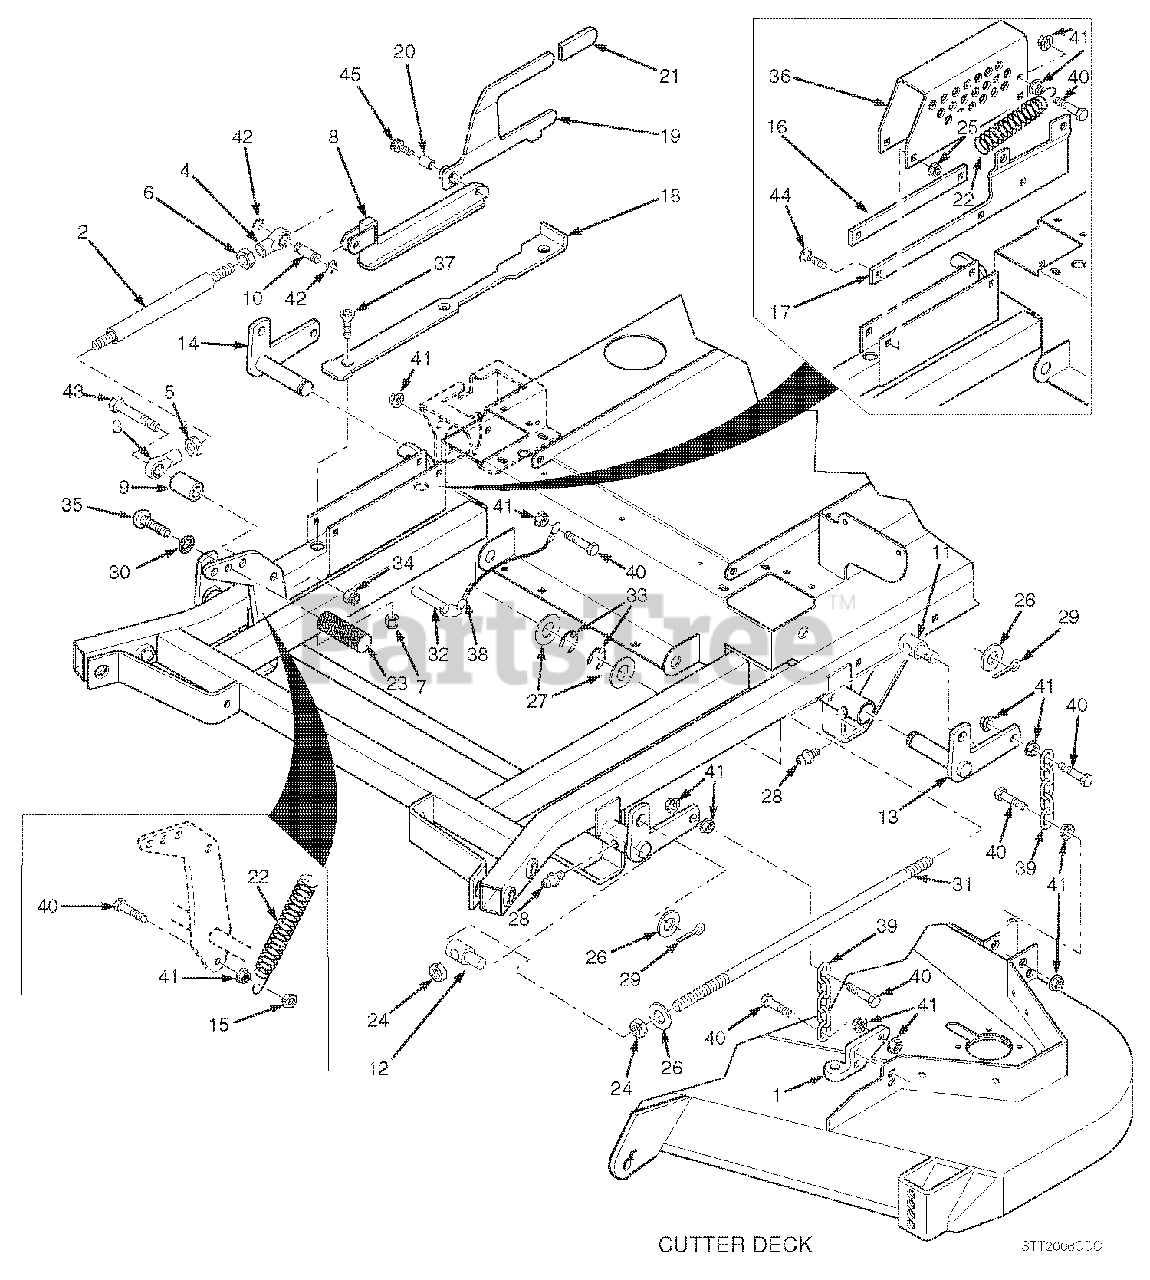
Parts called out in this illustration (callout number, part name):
1	Lever Assembly, Deck Level
2	Link, Deck Lift
3	Rod End, Female - 1/2-20 RH
4	Rod End, Female - 1/2-20 LH
5	Nut, Jam 1/2-20 RH
6	Nut, Jam 1/2-20 LH
7	Nut, 3/8-16 Elastic Stop
8	Slide Weldment, Height Adjustment
9	Spacer, Decklift Pedal
10	Pin, Decklift
11	Swivel Joint, LH
12	Swivel Joint, RH
13	Bellcrank Weldment, LH Rear
14	Bellcrank Weldment, RH Rear
15	Locknut, 3/8-16 Center Lock
16	Guide, Short
17	Guide, Long
18	Lockplate, Decklift
19	Deck Latch
20	Bushing, .502" ID.
21	Grip, Deck Latch
22	Spring, Helper
23	Foot Pedal, Height Adjustment
24	Nut, Hex 5/8-11
25	Nut, Hex Serrated Flange 5/16-18
26	Flatwasher, 5/8" (.656 x 1.312 x .095")
27	Flatwasher, 1" (1.062 x 1.50 x .048")
28	Grease Fitting
29	Cotter Pin, 3/16 x 1"
30	Lockwasher, 5/8"
31	Stud, 5/8-11 x 22.0"
32	Ring Pin, 1/2 x 3.06"
33	Ring, Retaining 1" External "E"
34	Nut, Hex Elastic Stop 1/2-13
35	Capscrew, 5/8-11 x 1-1/2"
36	Bracket, Cutting Height Adjustment
37	Screw, Cap 5/16-18 x 3" FHHS
38	Lanyard, Deck Height Pin
39	Chain
40	Bolt, Hex Head 3/8-16 x 1-1/2"
41	Nut, Hex Serrated Flange 3/8-16
42	Ring, Retaining 1/2" External "E"
43	Bolt, Hex Head 1/2-13 x 3"
44	Bolt, Carriage 5/16-18 x 1"
45	Bolt, Shoulder 1/2 x 3/4"
